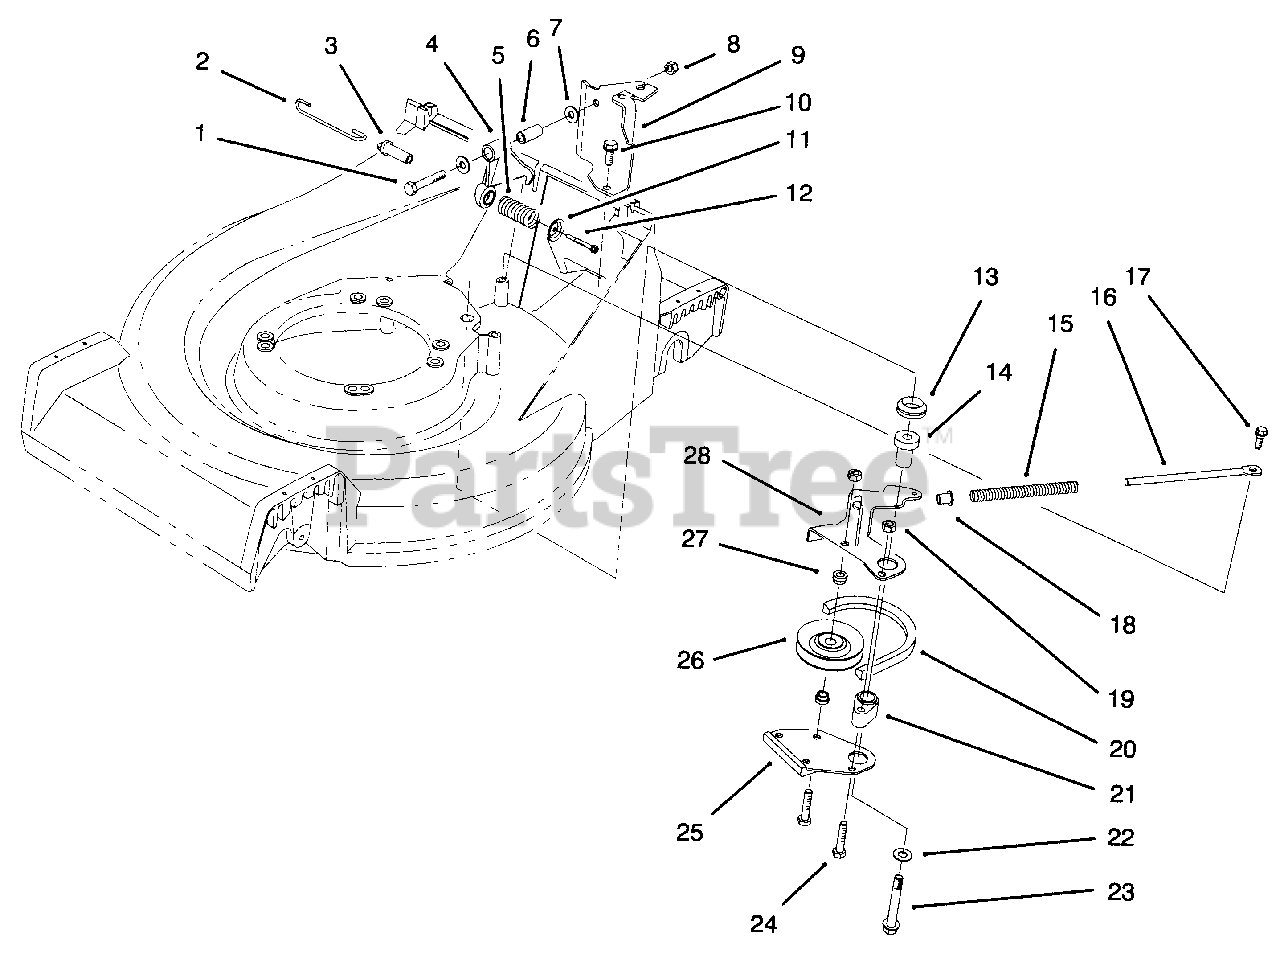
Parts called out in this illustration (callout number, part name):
1	Screw-Hex Hd. Cap
2	Link-Control
3	Pin-Spring
5	Spring-Compression
6	Bushing-Bellcrank
7	Washer-Flat
8	Nut-Flange
9	Bracket-Cable Support
10	Screw-Tapping
11	Retainer-Spring
12	Screw-Hex Washer Hd.
13	Seal-Ring "V"
15	Spring-Compression
16	Rod-Spring Brake
17	Bolt-Shoulder
18	Bushing-Flange
19	Nut-Lock
21	Hub-Plate BBC Brake
22	Washer-Flat
23	Screw-Thread Forming
24	Screw-Hex Hd. Cap
25	Shoe-Brake
26	Pulley-Idler
27	Hub-Pulley Idler
28	Lever-Brake
